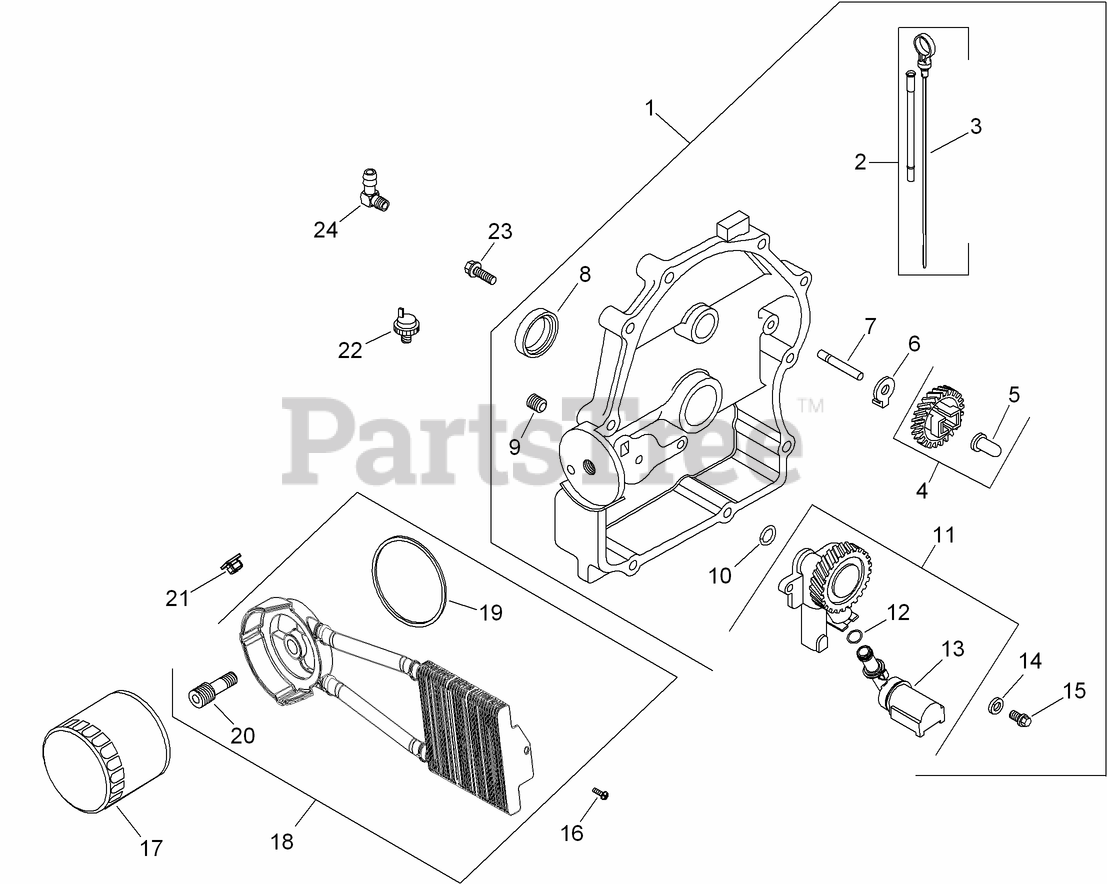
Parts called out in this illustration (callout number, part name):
1	CLOSURE PLATE ASM (INCLUDES 2-15)
2	DIPSTICK AND DIPSTICK TUBE ASM (INCLUDES 3)
3	Dipstick
4	GOVERNOR GEAR W/PIN KIT (INCLUDES 5)
5	PIN-REGULATING, GOVERNOR
6	TAB-LOCKING
7	SHAFT-GEAR, GOVERNOR
8	SEAL-OIL
9	PLUG-PIPE, COUNTERSUNK (1/8)
10	O-Ring
11	OIL PUMP ASM (INCLUDES 12, 13)
12	O-RING (OIL PICK-UP)
13	TUBE-PICK UP, OIL
14	WASHER-FLAT (6 MM)
15	SCREW-FLANGE, THREAD FORMING (M6X1.0X25)
16	SCREW-TAP (M6X1.7X18)
17	Filter-Oil
18	OIL COOLER KIT (METAL) (INCLUDES 19, 10)
19	O-RING
20	NIPPLE-FILTER, OIL
21	NUT-PLASTIC (BLACK)
22	SWITCH-PRESSURE, OIL
23	SCREW-FLANGE (M8X1.25X45)
24	Connector-Hose, 90 Deg
